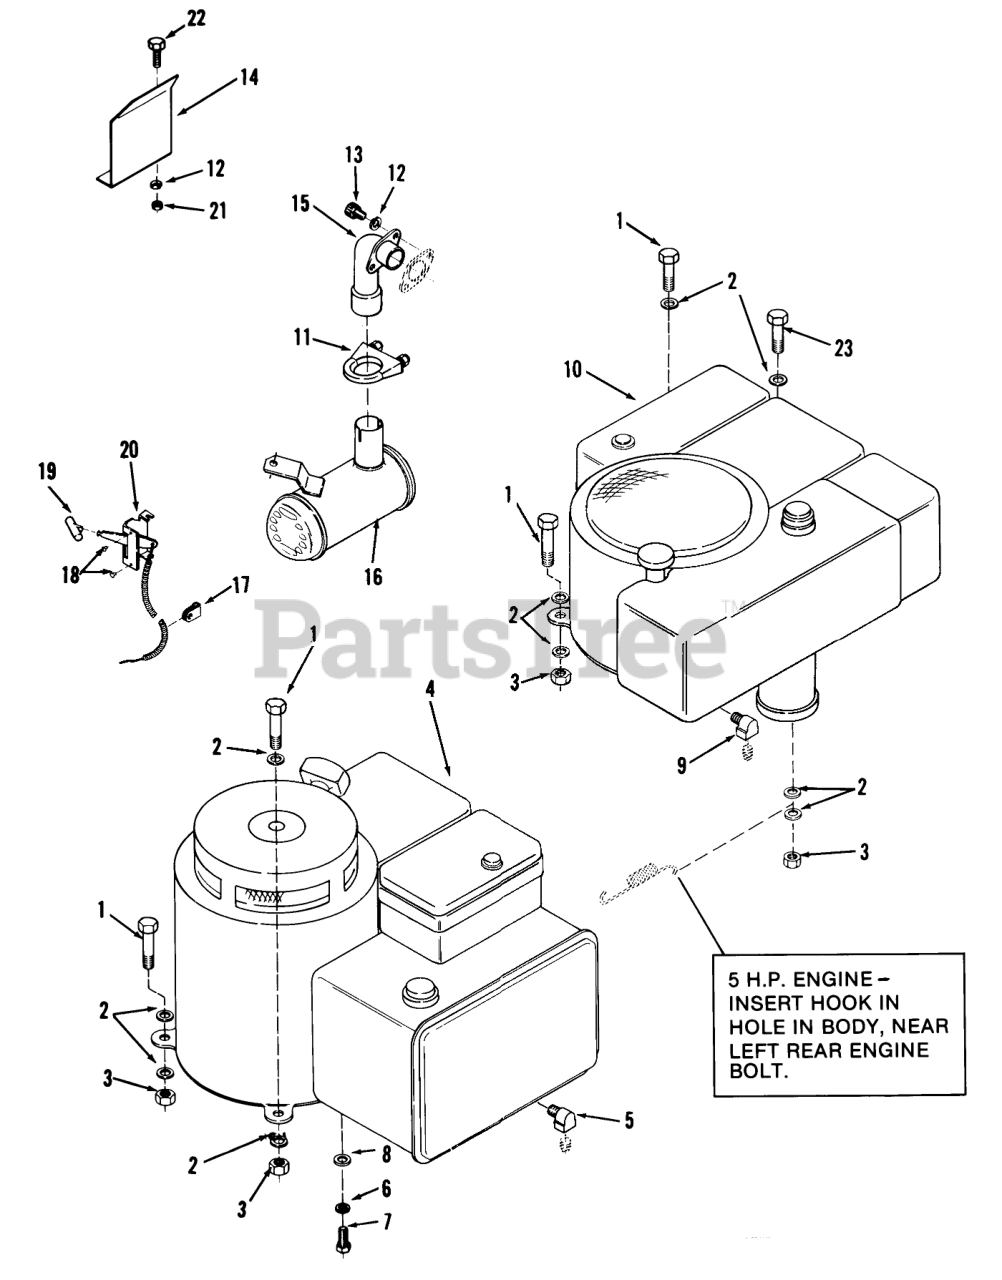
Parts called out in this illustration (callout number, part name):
2	WASHER 5/16 SAE
2	WASHER
4	Engine 5 H.P.-B S Model 130902 Type 0584-01
5	Street Elbow
10	Engine 8 H.P.-B S Model 191707 Type 5663-01 A-81 Only
10	Engine 11 H.P.-B S Model 252707 Type 0207-01 A-111 Only
13	SHCS 5/16-18X.625
17	THROTTLE CONTROL CLP
18	RIVET
